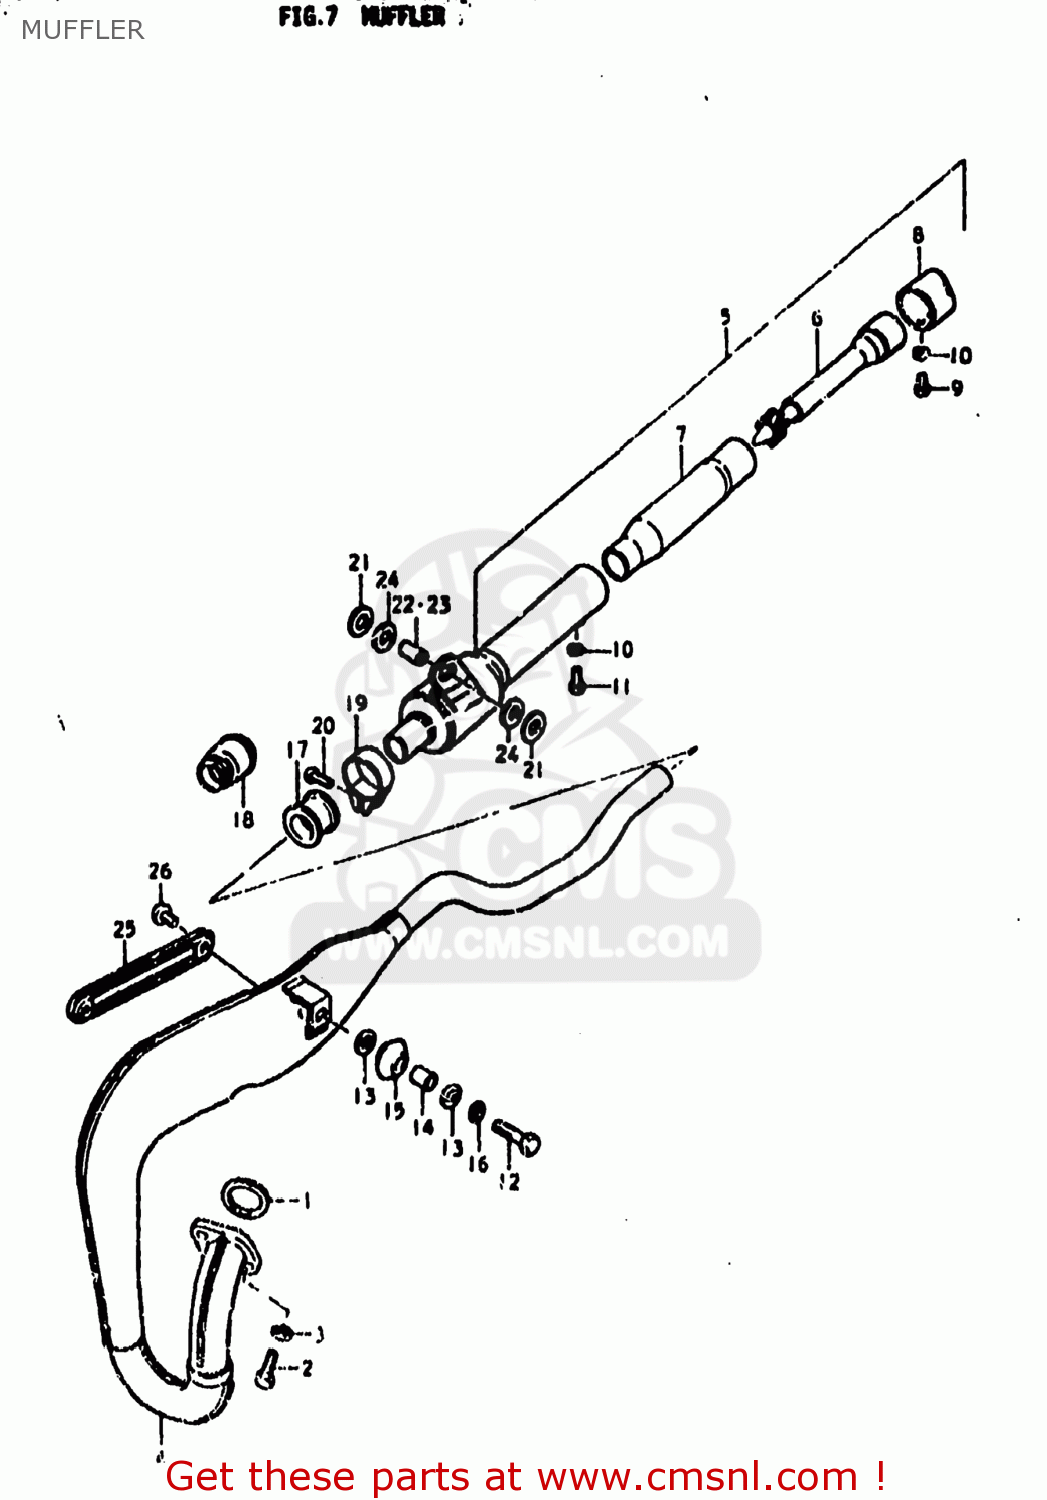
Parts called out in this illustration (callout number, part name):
1	GASKET,EXHAUST PIPE (NAS)
2	BOLT
3	LOCK WASHER
4	BODY,MUFFLER
5	MUFFLER ASSEMBLY
6	TUBE,CLEAN OUT
7	SHELL,ARRESTER
8	CUTTER,SPARK ARRESTER
9	SCREW
10	LOCK WASHER
11	SCREW
12	BOLT (8X30)
13	WASHER (8.7X22X2)
14	SPACER (8X12X15)
15	DAMPER,MUFFLER,FR
16	LOCK WASHER
17	CONNECTOR,MUFFLER
18	CONNECTOR,MUFFLER
19	CLAMP
20	SCREW
21	WASHER
22	SPACER (8.6X13.8X9)
23	SPACER (8.6X13.8X9)
24	CUSHION
25	COVER,MUFFLER
26	SCREW
